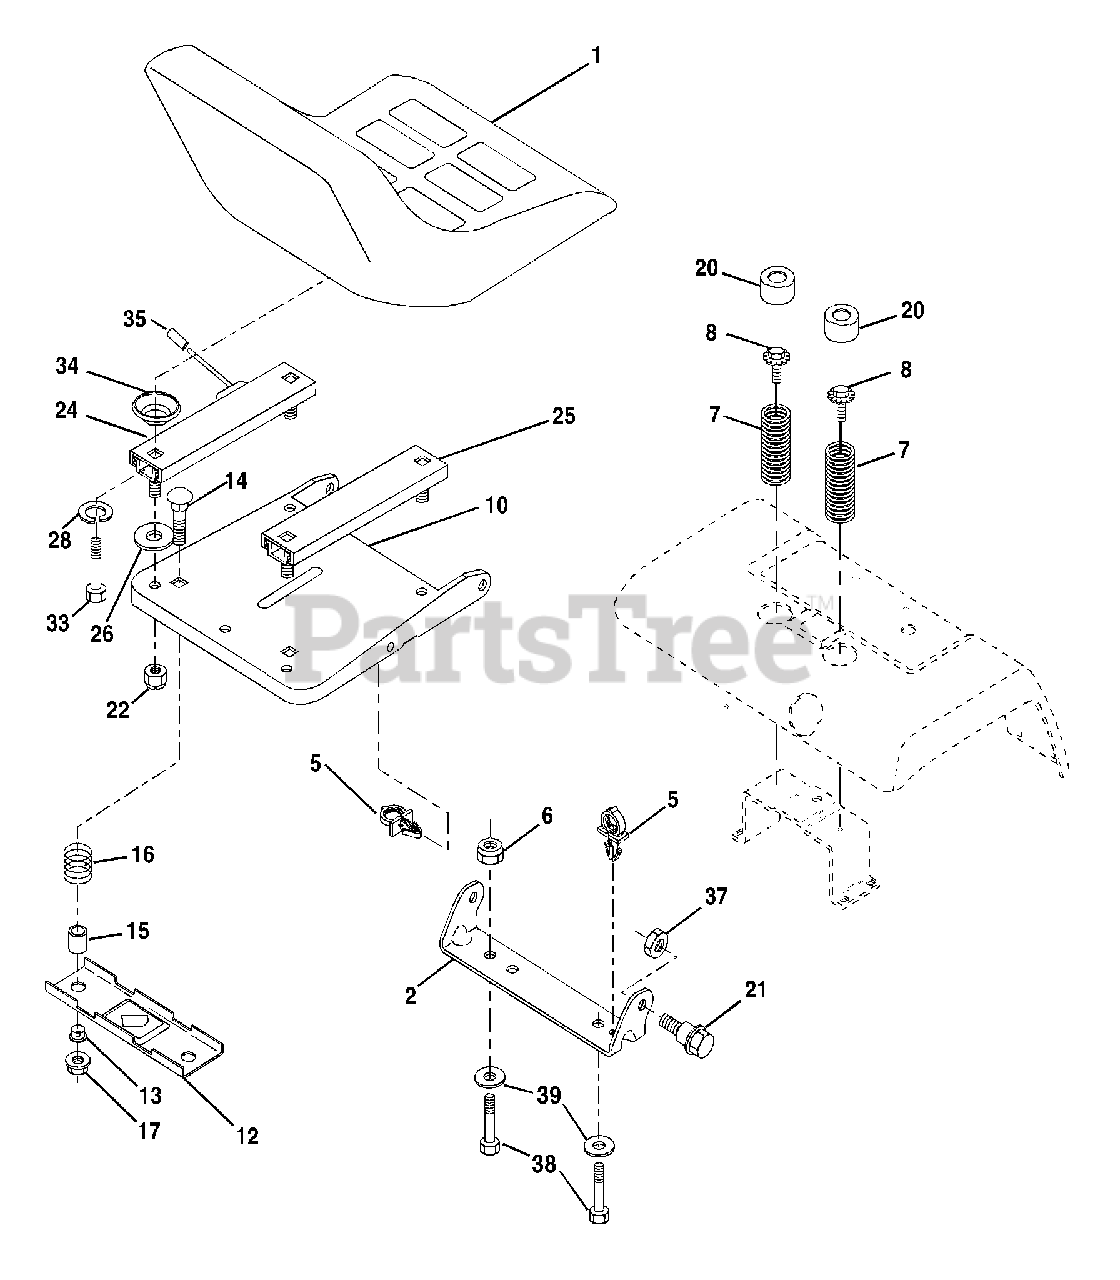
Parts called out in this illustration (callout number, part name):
1	Seat
2	Bracket, Pivot Seat
5	Clip, Push In Hinged
6	Nut, Crownlock 3/8-16
7	Spring, Seat Cprsn
8	Bolt 5/16-18 Unc x 3/4
10	Pan, Seat
12	Bracket, Mounting Switch
13	Bushing, Snap
14	Bolt, Carriage 1/4-20 x 1-1/2
15	Spacer, Split
16	Spring, Cprsn
17	Nut, Lock 1/4 Lge Flg Gr. 5
20	Cap, Spring Seat
21	Bolt, Shoulder 5/16-18
22	Nut, Crownlock 5/16-18
24	Track Slide Seat LH Locking
25	Track Slide Seat RH Free
26	Washer 11/32 x 5/8 x 12 Ga.
28	Washer Split
33	Bolt Fin Hex 5/16-18 x 1
35	Cap Vinyl
38	Bolt Fin Hex 3/8-16 Unc x 1
39	Washer Flat 13/32 x 1 x 10 Ga
